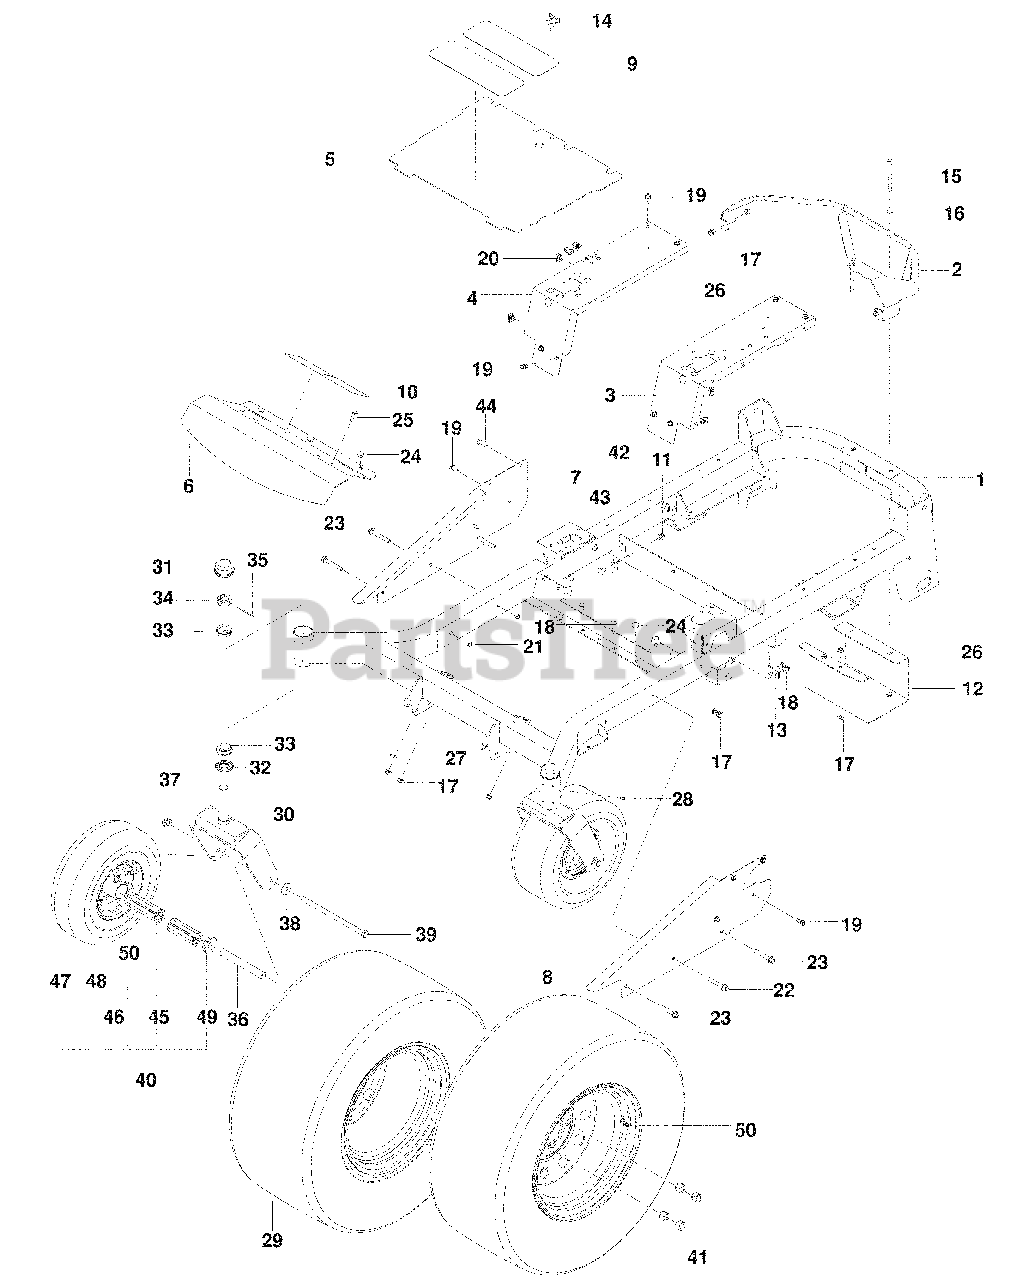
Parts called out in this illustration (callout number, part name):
1	FRAME w/ SAFETY DECALS
2	GUARD, REAR
5	PLATE, FLOOR w/ DECALS
6	PLATE, FOOTREST
9	PAD, ABRASIVE LG
10	PAD, ABRASIVE SM
11	NUT 3/8-16 HEX FLG NYLOC
12	SHIELD, MUFFLER
13	STOP, DECK
14	KNOB w/ STUD
15	HCS 5/16-18 x 4
16	WASHER 5/16 SAE FLAT
17	NUT 5/16-18 FLANGE NYLOC
18	BOLT, RD HD 5/16-18 x ¾
19	BOLT 5/16-18 x ¾ THD FRM
20	RETAINER, U TYPE
21	NUT 3/8-16 HEX JAM NYLOC
22	SCREW, HX FLG 3/8-16 x 2¾
23	SCREW, HX FLG 3/8-16 x 2½
24	GROMMET, BUMPER
25	BOLT, RD HD 5/16-18 x 1
26	HHFS 5/16-18 x ¾
29	WHEEL ASSY, REAR
30	YOKE, CASTER
31	GREASE CAP
34	SLOTTED JAM NUT 1"-14
35	COTTER PIN 1/8 x 2
36	SPACER, PIVOT
37	NUT ½-13 HEX FLG NYLOC
38	WASHER ½ FLAT ZD
39	HCS ½-13 x 9½
40	TIRE ASSM
42	BRACKET, DAMPENER
43	BOLT, RD HD 3/8-16 x ¾
44	HHFS 5/16-18 x 1¼ TPBLT
45	CAGE BEARING 3¼
46	ZERK
47	TIRE, CASTER
48	RIM, CASTER TIRE
49	BEARING, FLANGE
